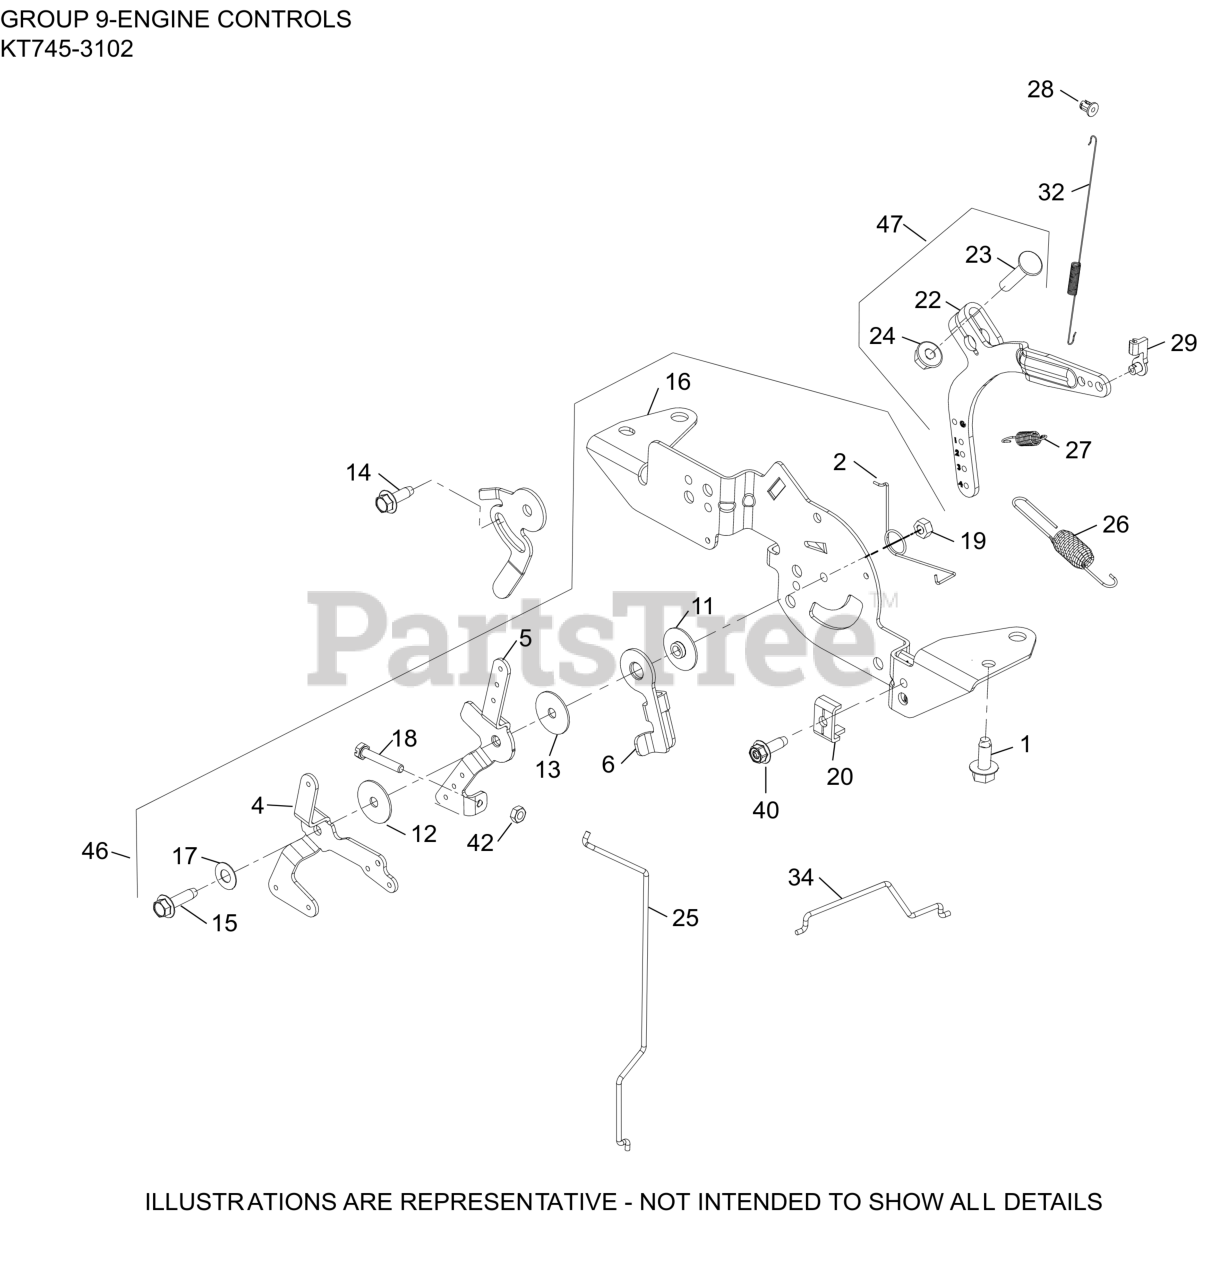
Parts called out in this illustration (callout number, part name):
1	SCREW, THREAD FORMING
2	SPRING, CHOKE RETURN
4	LEVER, CHOKE
5	LEVER, THROTTLE CONTROL
6	LEVER, THROTTLE ACTUATOR
11	SPACER, CONTROL ASSEMBLY
12	WASHER, FLAT 5.5 MM
13	WASHER, FLAT 5 MM
14	SCREW, THREAD FORMING
15	SCREW, THD FRM-USE 25 086 473-S
16	BRACKET, SPEED CONTROL
17	WASHER, SPRING 1/4"
18	SCREW, SLT HD CAP M4X0.7X25
19	NUT, LOCK M5X.8
20	CLAMP, CABLE CABLE
22	LEVER, GOVERNOR - (#2409069S)
23	BOLT, RD HD SQ NECK M6X1.0X25
24	NUT, FLG M6X1.0
25	LINKAGE, CHOKE
26	SPRING, GOVERNOR (ORANGE)
27	SPRING, GOVERNED IDLE
28	BUSHING, LINKAGE RETAINING
29	BUSHING, THROTTLE LINKAGE
32	SPRING, LINKAGE
34	LINKAGE, THROTTLE
40	SCREW, THREAD FORMING
42	NUT, M4X0.7
46	CONTROL ASSEMBLY, DUAL WIRE
47	LEVER, GOVERNOR ASSEMBLY
